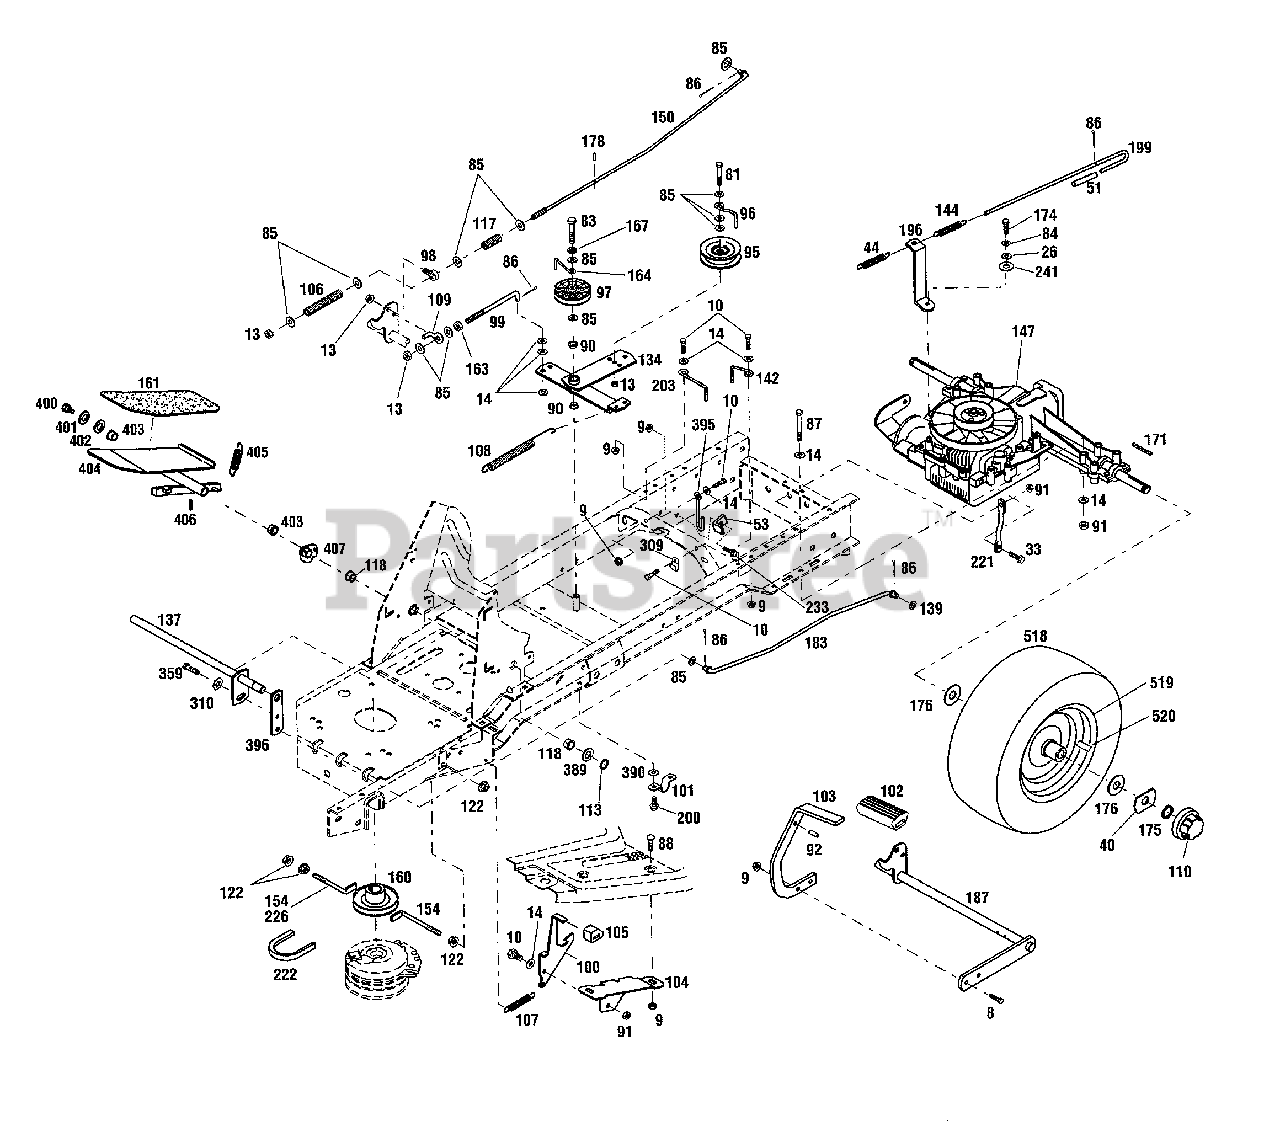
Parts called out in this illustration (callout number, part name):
8	Hex Head Screw, 5/16-18 x 1
9	Flange Nut, 5/16-18
10	Hex Head Screw, 5/16-18 x 3/4
13	Locknut, 3/8-16
14	Flat Washer, 5/16
26	Flat Washer, 1/4
33	Flange Lock Screw, 5/16-18 x 3/4
40	Special Washer, 3/4 x 2-1 /2
44	Extension Spring
51	Grip
53	Stop Bracket
81	Hex Screw, 3/8-16 x 2
83	Hex Screw, 3/8-16 x 1-3/4
84	Locknut, 1/4
85	Flat Washer, 3/8
86	Cotter Pin, 3/32 x 3/4
87	Hex Screw, 5/16-16 x 2-3/4
88	Carriage Bolt, 5/16-18 x 5/8
90	Nyliner Bushing
91	Locknut, 5/16-18
92	Drive Pin, 5/16 x 3/4
95	Idler Pulley
96	Belt Guide
97	Idler Pulley
98	Swivel
99	Clutch Rod
100	Brake Lock Latch
101	Clip, 3/4
102	Foot Pedal Pad
103	Brake Pedal
104	Brake Lock Bracket
105	Brake Pad
106	Compression Spring
107	Extension Spring
108	Extension Spring
109	Pivot Rod
110	Hub Cap
113	Retaining Ring
117	Compression Spring
118	Flange Bearing, 5/8
122	Flange Nut, 3/8-16
134	Idler Arm
137	Hydro Pivot Shaft
139	Flat Washer, 3/8
142	Belt Guide
144	Extension Spring
147	Transmission, Peerless Model VST 205
150	Brake Rod
154	Clutch Retainer
160	Engine Pulley
161	Foot Pedal Pad
163	Hex Nut, 3/8-18
164	Belt Guide
167	Lockwasher, 3/8
174	Hex Head Screw, 1/4-28 x 1
175	Retaining E-ring, 5/8
176	Flat Washer, 3/4 x 1-7/8
183	Hydro Control Rod
187	Brake Pedal
196	Dump Valve Arm
199	Dump Valve Rod
200	Flange Lock Screw, 5/16-18 x 3/4
203	Belt Guide
221	Transmission Support
226	Belt Guide
233	Flange Screw, 5/16-18 x 5/8
241	Special Flat Washer
309	J Clamp
310	Special Lockwasher
359	Hex Head Screw, 3/8-18 x 7/8
389	Flat Washer, 5/8
390	Flat Washer, 3/8
395	Brake Rod Guide
396	Control Arm
400	Shoulder Screw, 5/8 x 2
401	Flat Washer, 5/8
402	Flat Washer, 5/8
403	Flange Bearing
406	Roll Pin
407	Cam Assembly
518	Tire, 20 x 8.00-10
520	Valve Stem
